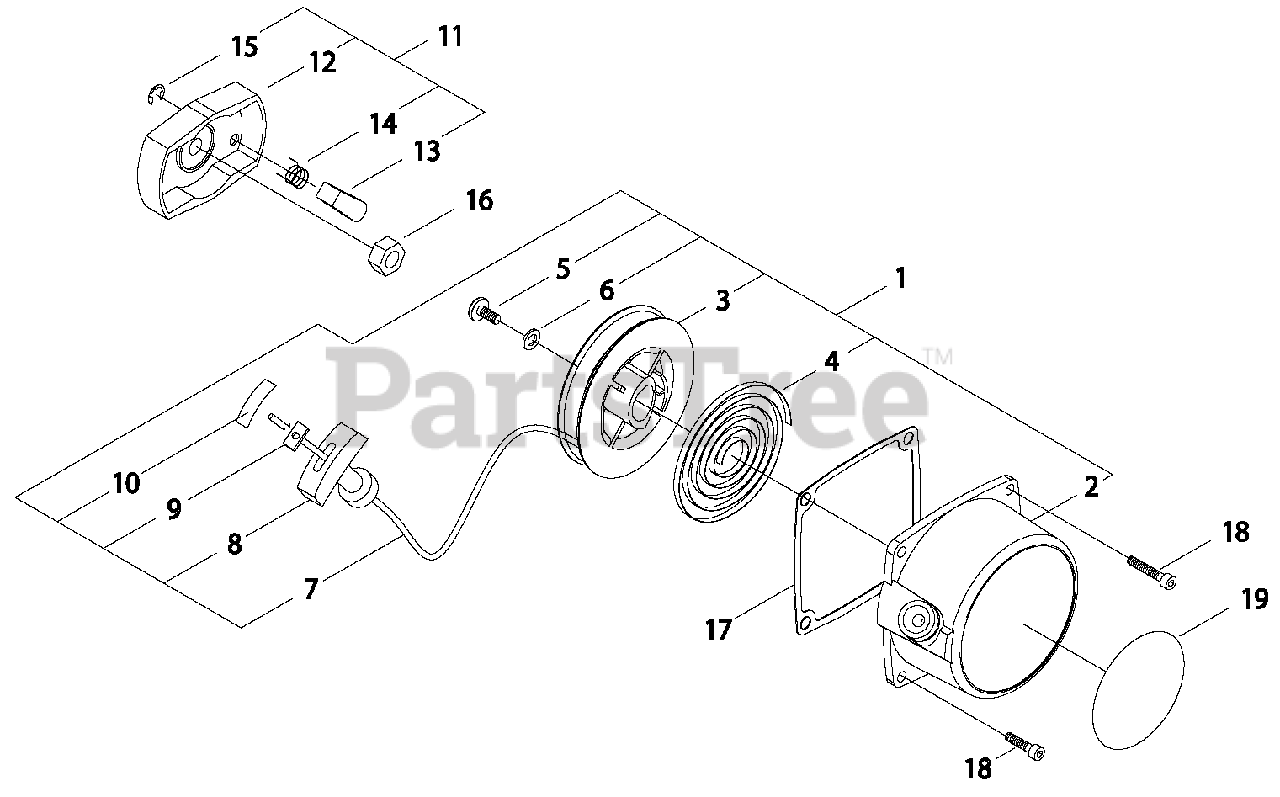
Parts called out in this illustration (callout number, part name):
1	STARTER ASSY, RECOIL
2	CASE, RECOIL STARTER
3	REEL, ROPE
4	SPRING, RECOIL
5	SCREW 5
6	WASHER
7	ROPE, STARTER
8	GRIP, STARTER
9	RETAINER, ROPE
10	TAPE
11	PULLEY ASSY, STARTER
12	PULLEY, STARTER
13	PAWL, STARTER
14	SPRING, RETURN
15	E-RING 4
16	NUT M8×H5
17	GASKET, RECOIL STARTER
18	BOLT M4×16
19	LABEL, TRADE
